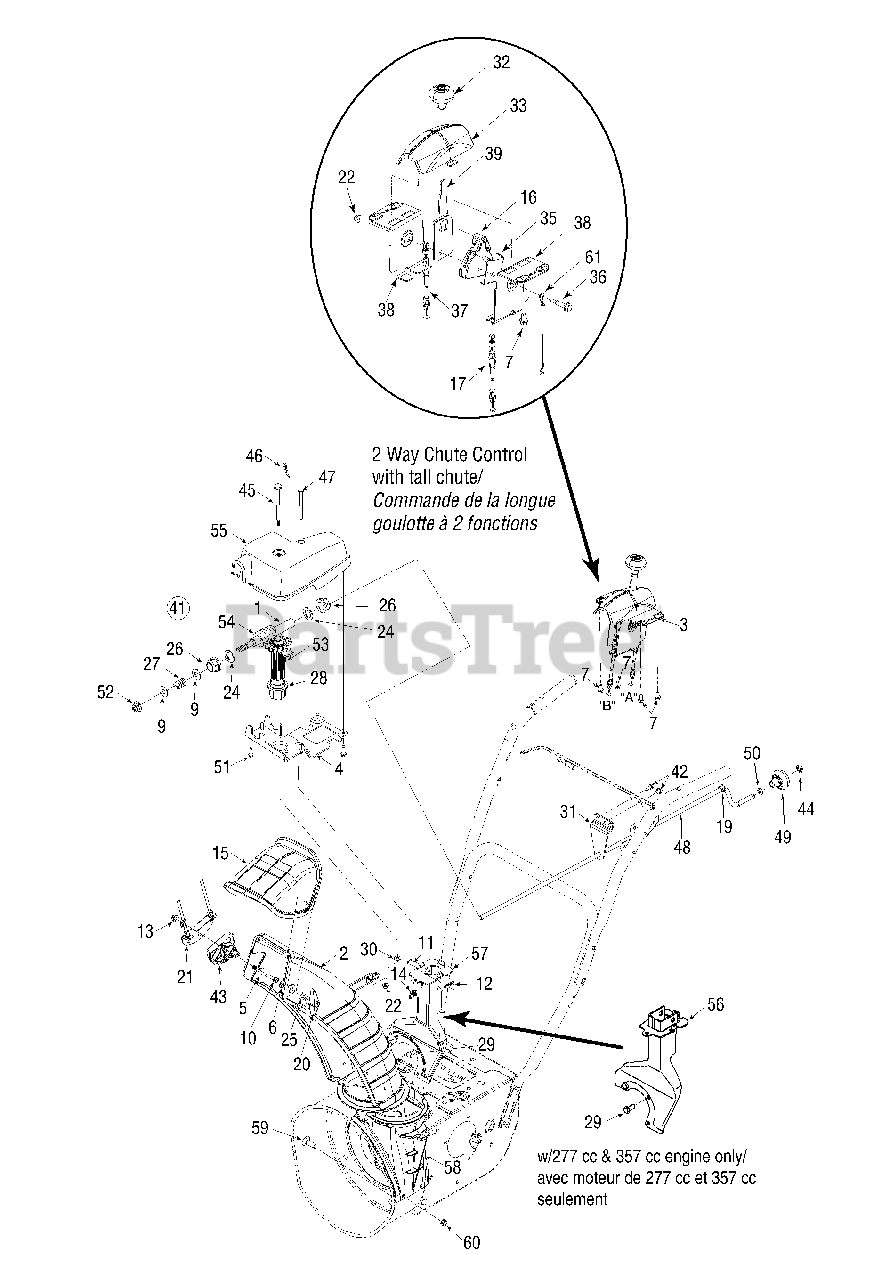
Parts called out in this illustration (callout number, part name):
1	Hex Shaft
2	Tall Lower Chute
3	2 Way Chute Control Assembly
4	Chute Gear Rotation Bracket
5	Carriage Bolt 5/16-18 x 1.50 Gr. 2
6	Carriage Screw 5/16-18 x 1.0
7	Hi-Lo Screw 1/4-15 x .5
9	Flat Washer .38 x .92 x .110
10	Hex Tapp Scr 1/4 x .75" Lg.
11	Clevis Pin 3/8 x 1.87
12	Bow Tie Cotter Pin
13	Flange Locknut 5/16-18 Gr. F Nylon
14	Wing Nut 1/4-20
15	Upper Chute w/ Label, Remote
16	Cable Guide
17	Cable - w/standard chute
17	Cable - w/tall chute
20	Handle Knob Assembly
22	Hex L-Flanged Nut 1/4-20 Gr. F Nylon
24	Flat Washer .625 x 1.0 x .067
25	Flat Washer .349 ID x .879 OD x .063
26	Hex Flg. Bearing
27	Compression Spring .39 x .60 x .88
28	Hex Bearing
29	Hex Hd. Cap Screw 5/16-24 x .75
30	Flat Washer .25 ID x .63 OD x .0515 HT.
33	Control Cover - 2 Way
35	Ground Chute Bracket
36	Flg Shlder Screw .310 x .995: 1/4-20
37	Cable - w/standard chute
37	Cable - w/tall chute
41	Gearbox Assembly
42	Hex Wash Hd TT Scr. 1/4-20 x .625
43	Cable Guide
44	Push Nut 3/8" Rod
45	Flg. Shoulder Screw .312 x 3.5: 1/4-20
46	Internal Cotter Pin
47	Hex. Hd. Cap Scr. 1/4-20 x 3.0 Gr. 5
48	Chute Crank .375 Dia. x 30.5" Lg.
50	Flat Washer .375 x .738 x .063
51	Hi-Lo Screw #12-16 x .75
52	Hex L-Flanged Nut 3/8-16 Gr. F Nylon
53	Gear 14 teeth helical w/hub
54	Worm - Nylon
55	Cover
56	Chute Sup. Bkt. Ass'y
57	Chute Support Bracket Ass'y
58	Chute Adapter
59	Carriage Screw 1/4-20 x .75 Gr. 5
60	Hex L-Flanged Nut 1/4-20 Gr. F Nylon
61	Harness Ground Wire
